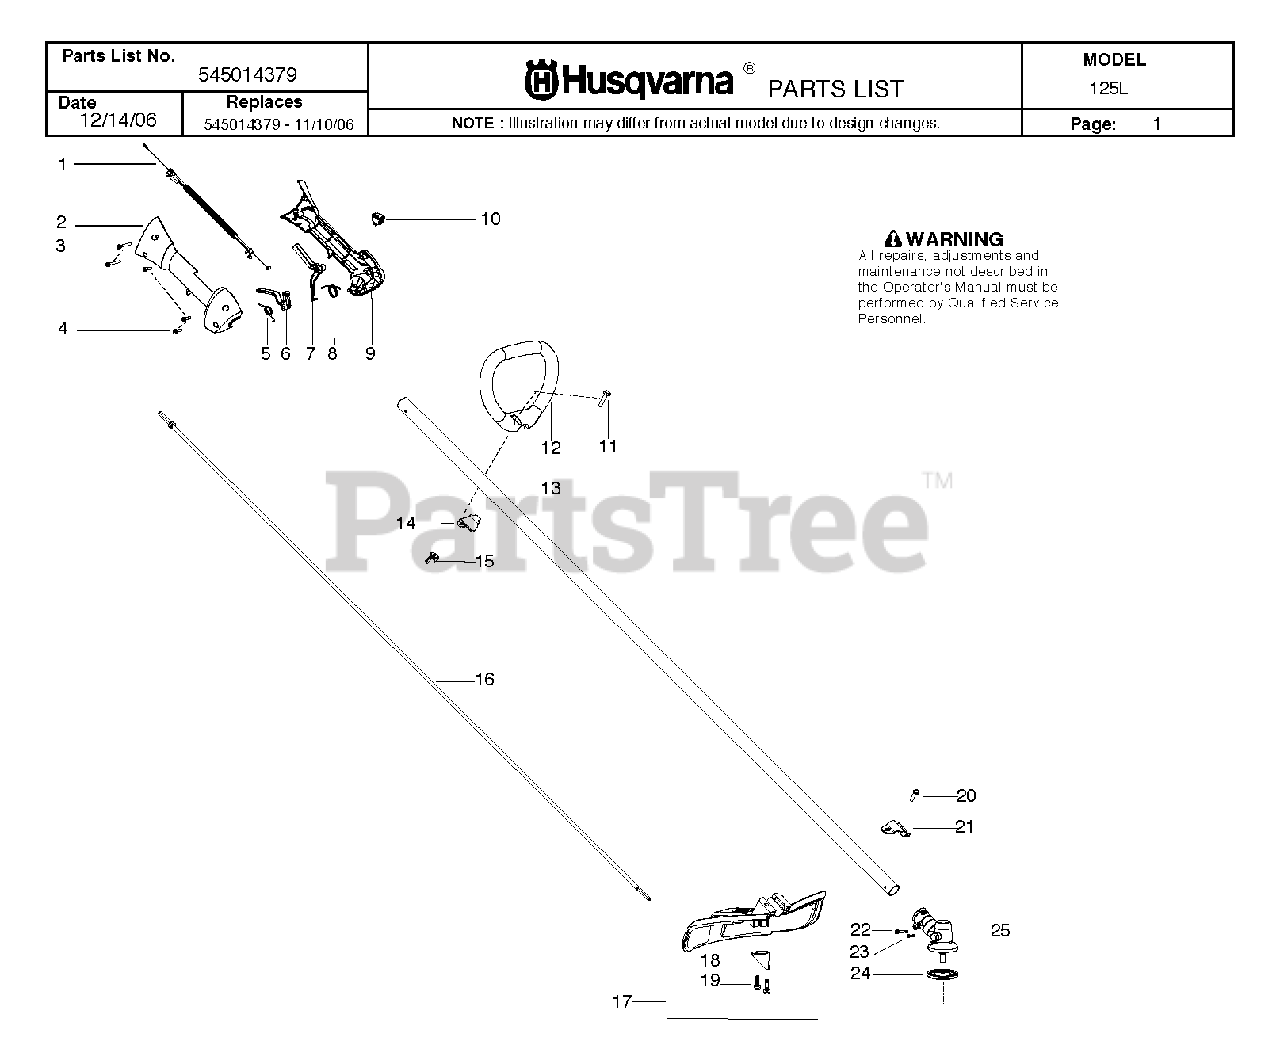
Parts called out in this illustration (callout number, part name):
1	Assy-Cable/Wire Harness
2	Housing-Throttle
5	Spring-Trigger
7	Lockout-Throttle
8	Spring-Lockout
9	Housing-Throttle
10	Kit-Switch
12	Handle-Assist
13	Kit-Driveshaft SST
14	Clamp-Handle
15	Wingnut
16	Flex shaft
17	Kit-Shield
18	Limiter-Line
21	Bracket-Shield
24	Driver Disc
25	Assy-Gearbox
